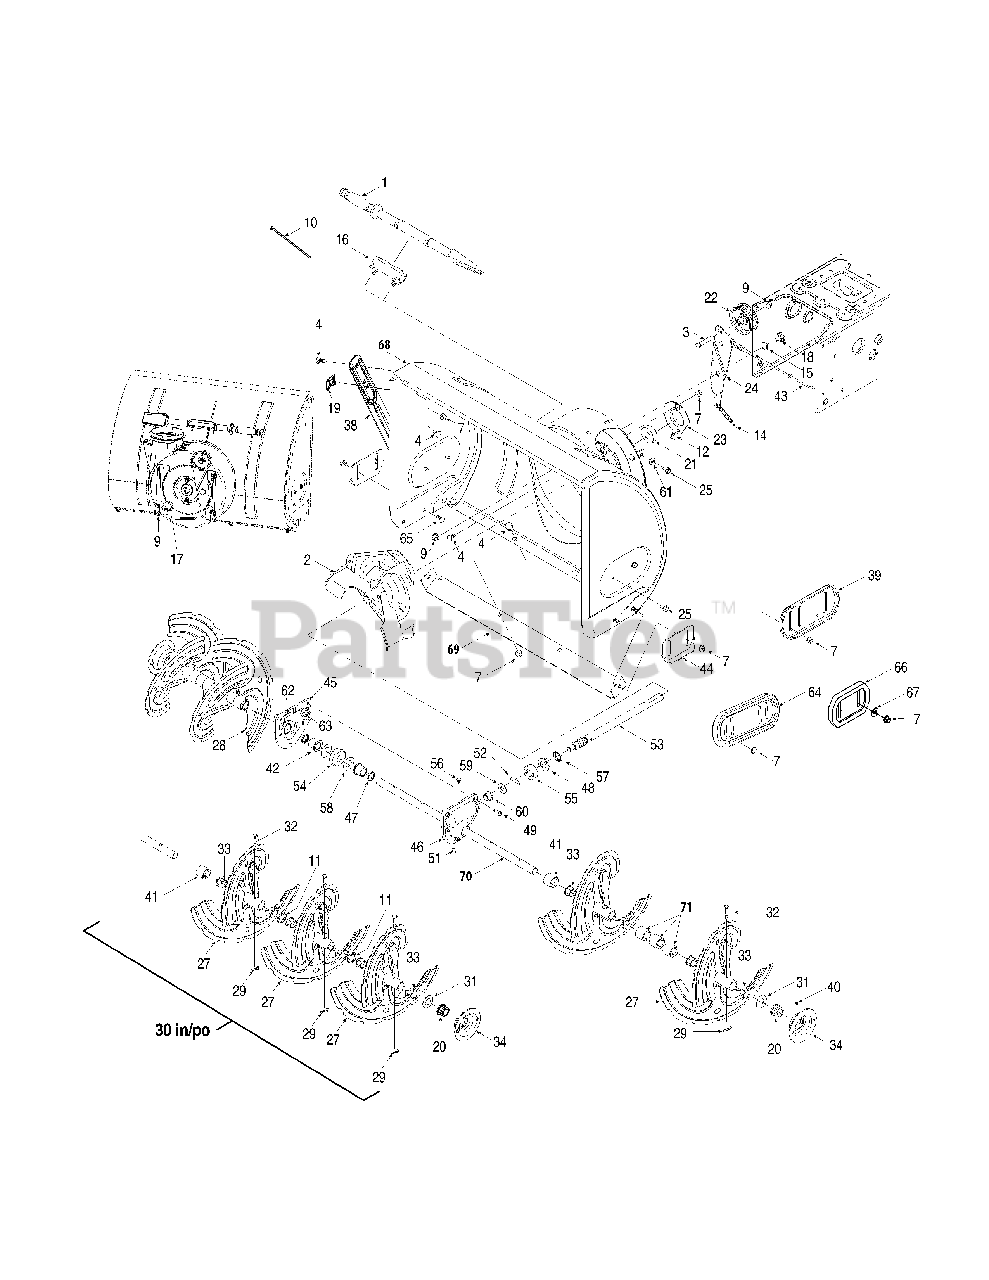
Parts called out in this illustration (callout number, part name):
1	Clean-Out Tool
2	Impeller Ass'y 12 po
3	Hex Screw 3/8-16 x 1.75
4	Carriage Bolt 5/16-18 x .75
7	Flange Locknut 5/16-18 Gr. F Nylon
9	Hex L-Flanged Nut 3/8-16 Gr. F Nylon
11	Spacer 1.25 x .75 x 3/16" Lg.
12	Push-on Nut .25 dia.
14	Extension Spring .38 OD x 4.59" Lg.
15	Wave Washer .660 ID x .88 OD x .010
16	Cleanout Tool Mount
17	Shld. Scr. .500 Dia. x .335" Lg.
18	Shoulder Scr .625 Dia x .170
20	Hex. Flange Brg. .751" I.D.
21	Self-aligning Bearing
22	Flat Idler Pulley 2.75" OD
23	Bearing Housing 1.85 ID
24	Auger Idler Brake Bracket
25	Hex TT Screw 3/8-16 x .75
27	Spiral Ass'y LH
28	Spiral Ass'y RH
29	Bow Tie Cotter Pin
31	Flat Washer .760 ID x 1.49 OD
32	Shear Pin .25 x 1.5 Gr. 2
33	Flange Bushing
34	Bushing Housing (w/grease Fitting hole)
38	Drift Cutter - optional
39	Reversible Slide Shoe (steel)
40	Grease Fitting (optional)
41	Spacer 1.25 x .75 x 1.00
42	Flange Bearing.75 ID x 1.0 OD x .975
43	Auger Clutch Cable
45	RH Reduced Auger Housing
46	LH Reduced Auger Housing
47	Oil Seal .75 x 1.0 x .125
48	Flange Bearing .75 ID x 1.00 OD x .50
49	Thd Forming Scr. 1/4-20 x .75
51	Hi Pro Key 3/16 x 5/8
52	Dowel Pin .25 OD x 1.2
53	Worm Shaft .75 OD
54	Worm Gear 20T (22", 24" & 26")
54	Worm Gear 20T (28" & 30")
55	Thrust Collar
56	Plug, 1/4 x .437
57	Oil Seal .75 x 1 x .131
58	Flat Washer .76 ID x 1.5 OD x .03
59	Fl. Washer .510 x 1.120 x .060
60	Flange Bearing .75 ID x 1.0 OD x .925
61	Cupped Washer .345 ID x .88 OD x .060
62	Loctite Seal ant 5699
63	Grease - Alvania EP Lead Free
64	Reversible Slide Shoe (plas tic)
65	Carriage Bolt 5/16-18 x .75 (w/steel slide shoes)
66	Small Reversible Slide Shoe (plas tic)
67	Flat Washer .349 ID x .879 OD x .063
68	Auger Housing - 24"
68	Auger Housing - 26"
68	Auger Housing - 28"
68	Auger Housing - 30"
69	Shave Plate - 24"
69	Shave Plate - 26"
69	Shave Plate - 28"
69	Shave Plate - 30"
70	Gearbox Assy - 24"
70	Auger Axle - 24"
70	Gearbox Assy - 26"
70	Auger Axle - 26"
70	Gearbox Assy - 28"
70	Auger Axle - 28"
70	Gearbox Assy - 30"
70	Auger Axle - 30"
